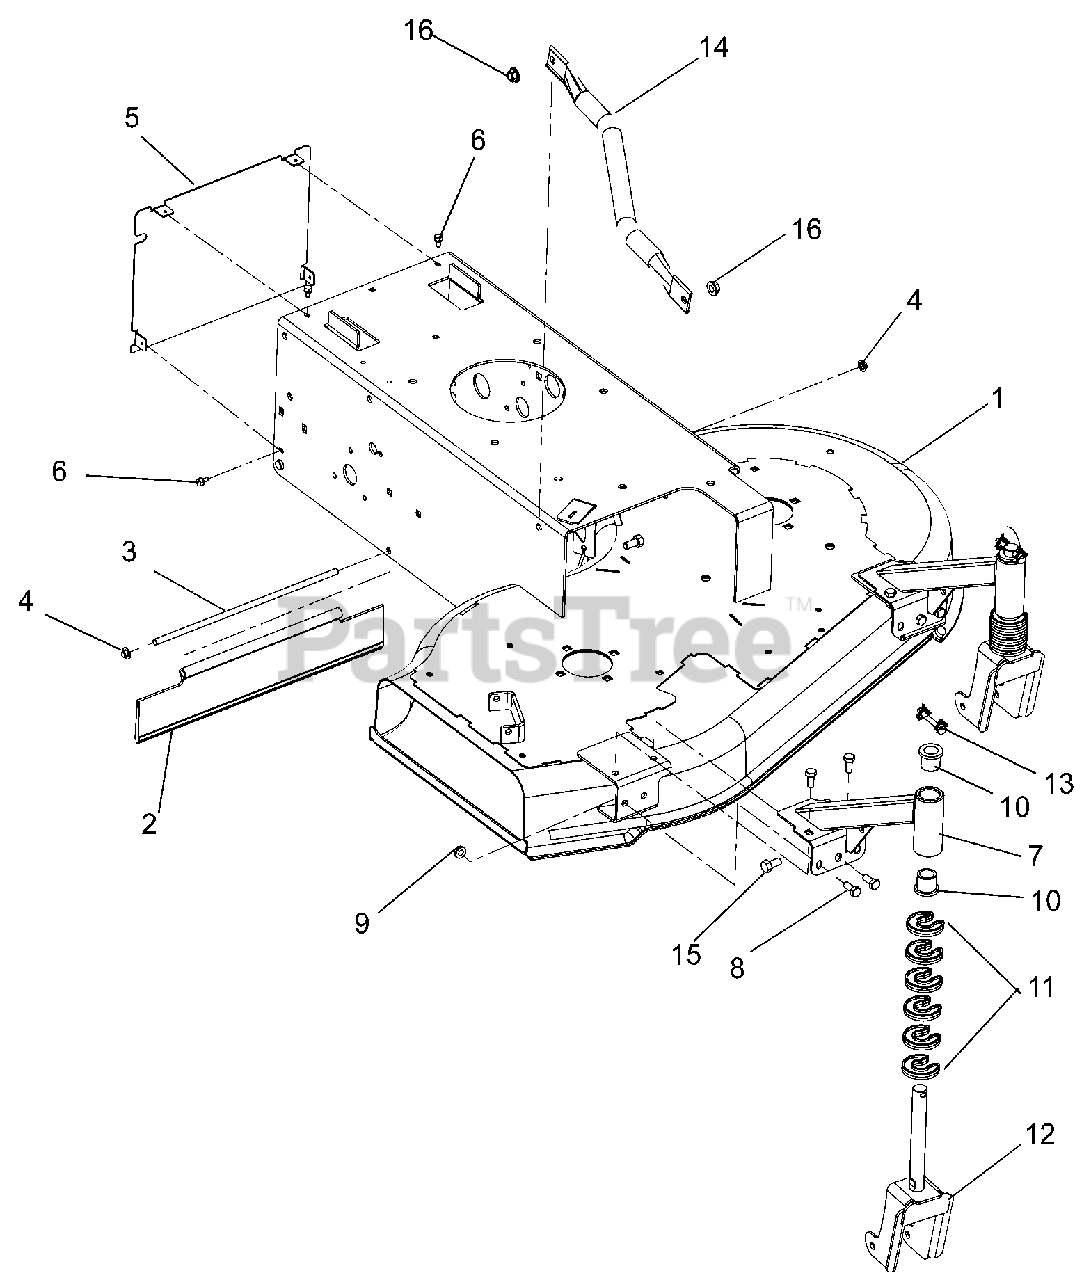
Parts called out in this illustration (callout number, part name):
1	Chassis, Wide Area Walk
2	Guard, Rear Swivel
3	Rod, Trailing Shield
4	Nut, Push .312 Dia. PAL
5	Cover, Rear Chassis
6	Screw, Tapping 10-24 x .375 Pre-Coat 80
7	Weldment, Caster Arm
8	Bolt, Hex .31-18 x .75
9	Nut, Locking Top Flange .31-18
10	Bushing 1.00 x .75 x 1.00
11	Clip, HOC Fixed
12	Fork, Caster
13	Pin, Lock .25 x 1.75
14	Strap, Frame Reinforcing
15	Bolt, Hex .38-16 x .75
16	Nut, Locking Top Flange .38-16
